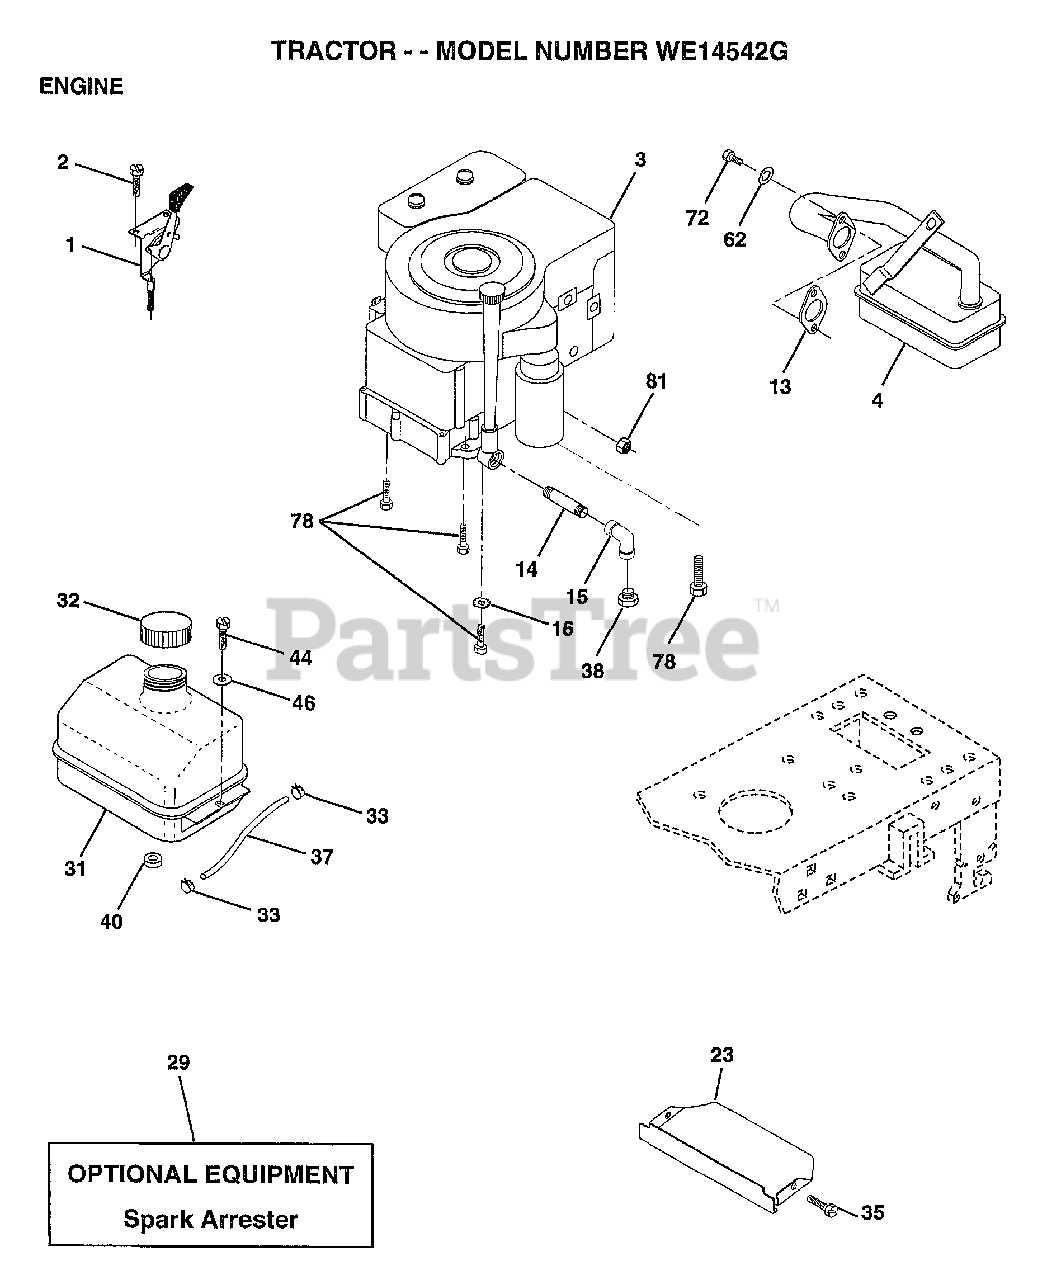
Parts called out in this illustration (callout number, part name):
1	CONTROL THROTTLE
2	SCREW LT
4	MUFFLER
13	GASKET ENG 1 313 LD TIN PLATED
14	PIPE NIPPLE
15	ELBOW
16	LOCKWASHER
23	SHIELD.BRN/DBR.GD
31	TANK.FUEL.LT.
32	CAP ASM FUEL
33	HOSE CLAMP
35	SCREW
37	LINE FUEL
44	SCREW HEX CRT
46	WASHER
62	LOCKWASHER
72	SCREW
78	SCREW
81	NUT
